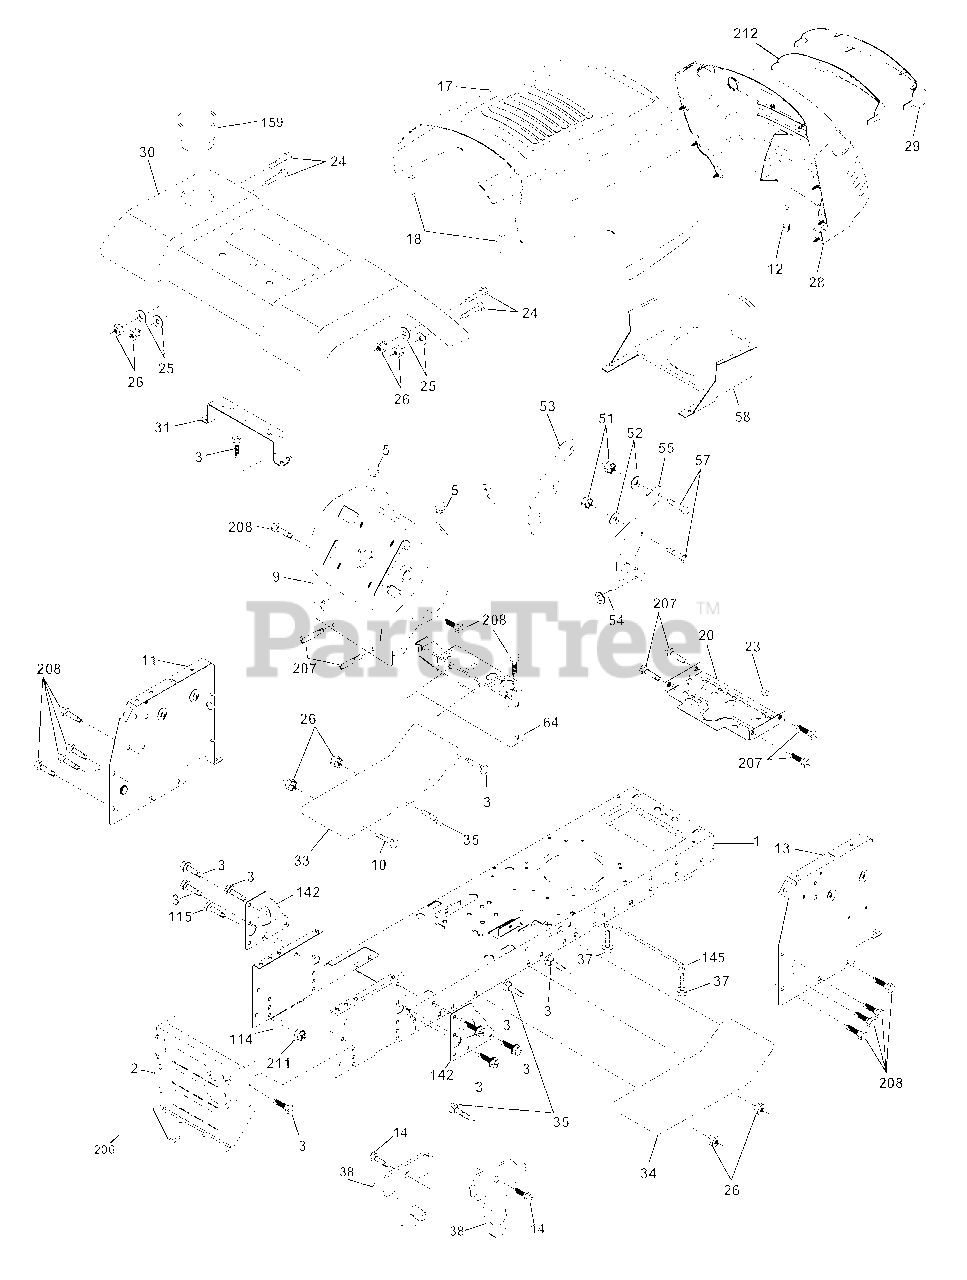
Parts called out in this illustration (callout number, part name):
1	Chassis
2	Drawbar
3	Screw 3/8-16x.75
5	Bumper Hood/Dash
9	Dash P/L
10	Bolt Carriage 3/8-16 x 1
11	Panel Dash Lh
12	Clip Tinnerman
13	Panel Dash Rh
14	Screw Thdrol 3/8-16 x 1/2
17	Hood LT/PL
18	Bumper Hood
20	Plate Mtg Battery Fuel Tank Fr
23	Bushing
24	Bolt Fin Hex 3/8-16 x 1 Gr 5
25	Washer 13/32 X 13/16 X 12 Ga
26	Nut Lock Hex W/Ins 3/8-16 Unc
28	Grille LT/PL
29	Lens LT/PL
30	Fender
31	Bracket Support Fender
33	Footrest Pnt Lh
34	Footrest Pnt Rh
35	Bolt Rdhd Sht Sqnk 3/8-16 x 3/4
37	Screw Thdrol 6/16-18 x 1/2 TYT
38	Bracket Asm. Pivot Mower Rear
51	Nut Lock Hex W/Ins 1/4-20
52	Washer 9/32 x 7/8 x 16 Ga.
53	Bracjet Grukke Lh
54	Screw Hex Wshd 8-18 x 7/8
55	Bracket Grille Rh
57	Bolt Hex 1/4-20 x 3/4
58	Duct Air
64	Dash Lower STLT
114	Keeper Belt Rear LH
115	Screw 3/8-16 x 1-1/4
142	Plate Reinforcement STLT
145	Rod Pivot Chassis/Hood
159	Cupholder
206	Bolt Shoulder 5/16-18
207	Screw Thdrol 5/16-18 x 1/2
208	Screw Thdrol 3/8-16 x 1/2
211	Nut Hexflange Lock
212	Insert Lens Reflect P/L LT
